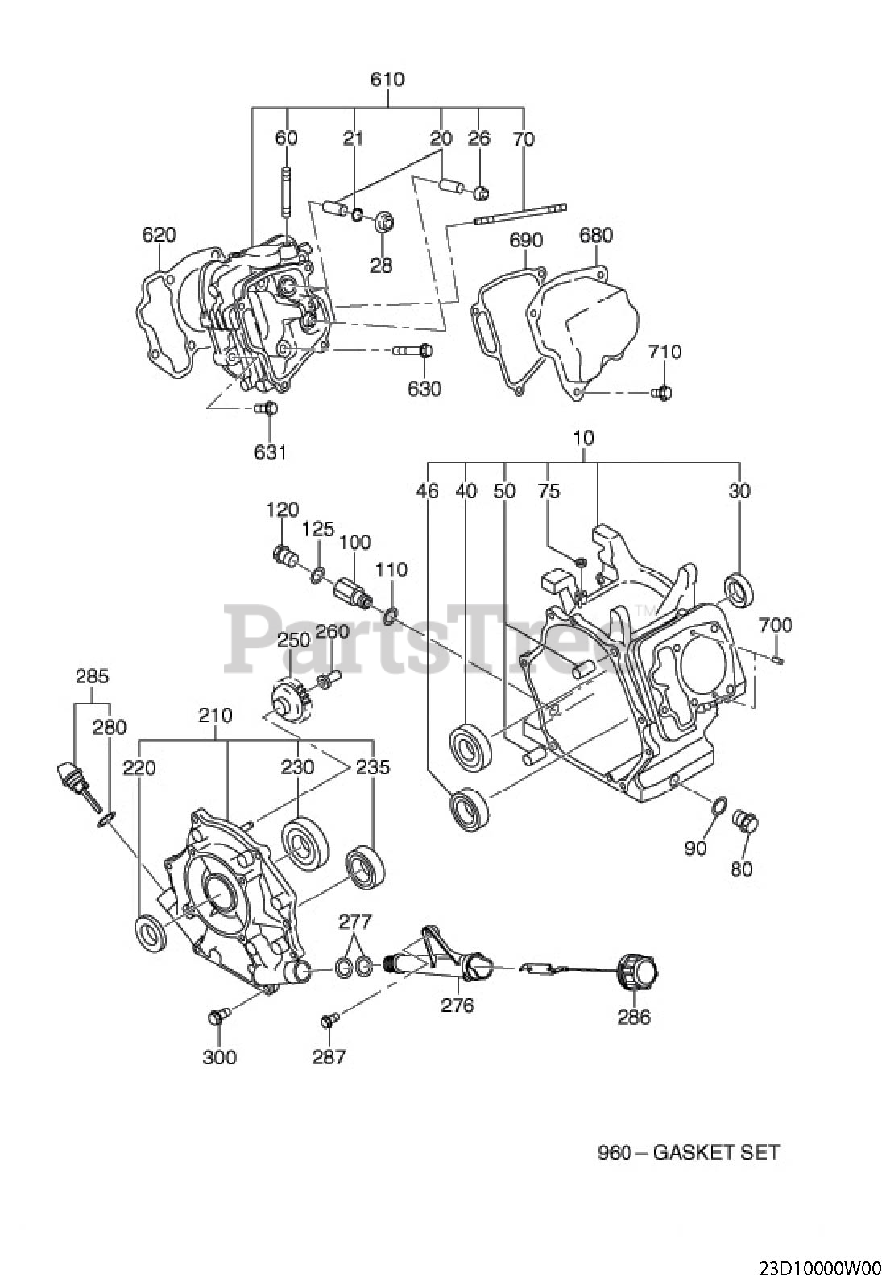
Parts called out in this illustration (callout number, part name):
10	CRANK CASE CP
21	CLIP
26	SEAL-EXH VALVE
28	RETAINER PLATE
30	OIL SEAL EH42PL
40	BALL BEARING
46	BALL BEARING
60	STUD
70	STUD
75	OIL SEAL
80	OIL DRAIN PLUG
100	UNION
110	SEAL WASHER
120	PLUG
125	SEAL WASHER
210	MAINBEARING COVER CP
220	OIL SEAL EH42PL
230	BALL BEARING
235	BALL BEARING
250	GOVERNOR GEAR CP
260	GOVERNOR SLEEVE
276	OIL FILLER CP
277	O-RING
280	GASKET
286	OIL GAUGE CP
287	FLANGE BOLT
300	FLANGE BOLT
610	CYLINDER HEAD AY
620	GASKET(HEAD)
630	FLANGE BOLT
631	FLANGE BOLT
680	ROCKER COVER CP
690	GASKET(ROCKER COVER)
700	DOWEL PIN
710	FLANGE BOLT
